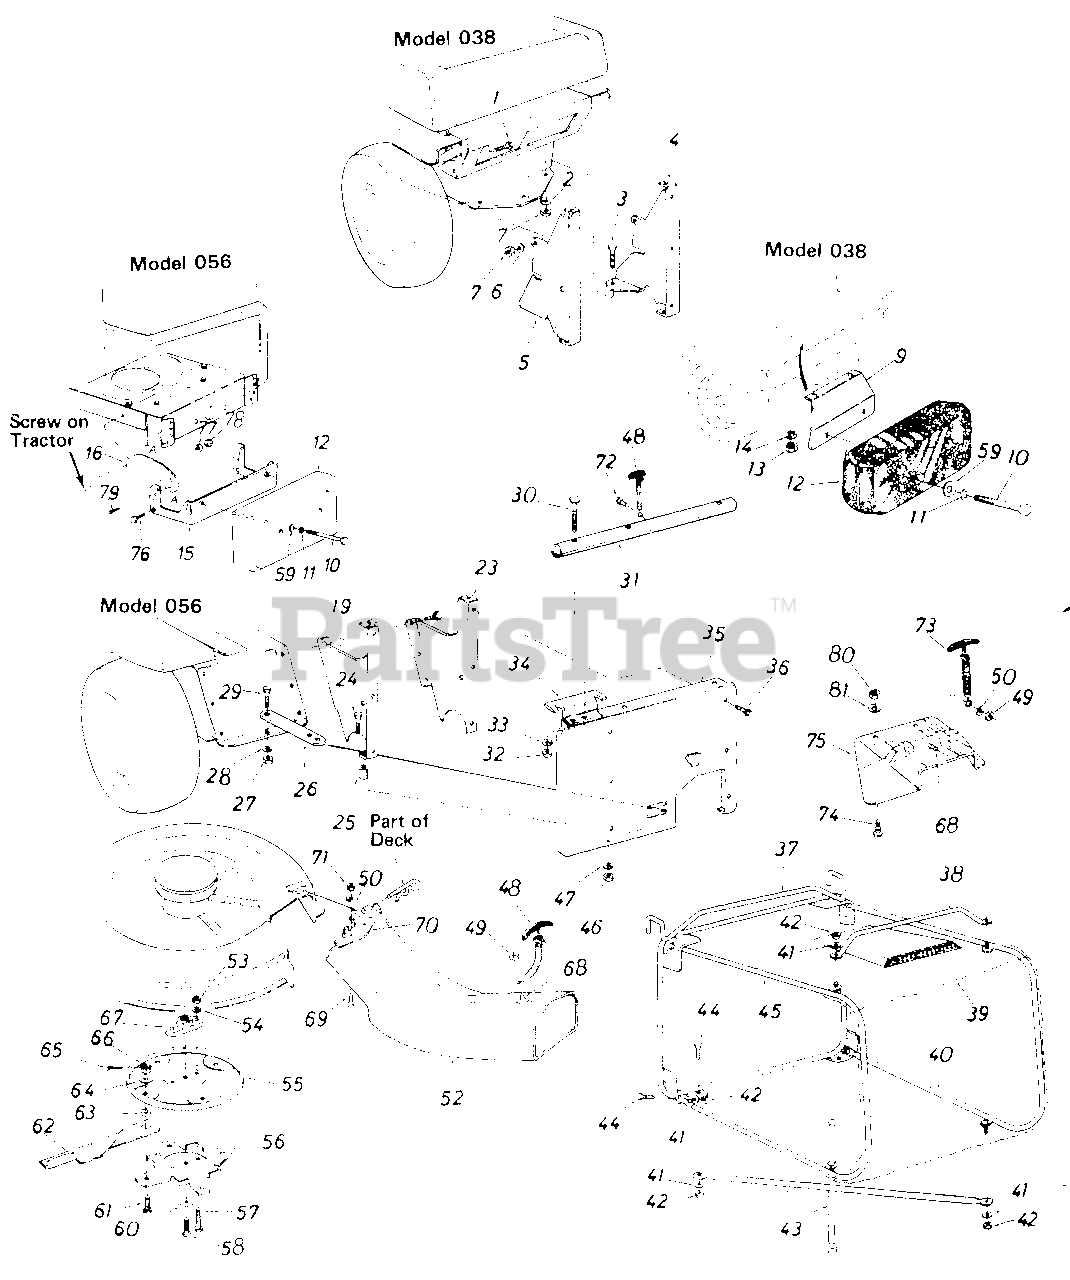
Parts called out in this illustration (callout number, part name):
1	Hex Bolt 5/16-18 x 1.0" Lg.
2	L.Wash. 5/16" I.D.
3	Hex Bolt 5/16-18 x 1.0" Lg.
4	Catcher Support Brkt R.H.
5	Catcher Support Brkt-L.H.
6	L.Wash. 5/16" I.D.
7	Hex Nut 5/16-18 Thd.
9	Counterweight Support Brkt. Ass'y .
10	Hex Bolt 3/8-16 x 4.5" Lg.
11	Beileville Wash. .40" I.D. x .88" 0. D.
12	Counterweight 38 Ibs.
13	Hex Nut 5/16-18 Thd.*
14	L.Wash. 5/16" I.D.
15	Counterweight Support Brkt. Ass'y.
16	Tie Strap
19	Catcher Support Brkt.-L.H.
23	Catcher Support Brkt.-R.H.
24	Hex Bolt 5/16-18 x 1.50" Lg."
25	Spacer .380" I.D. x .47" O.D. x 1.0" Lg.
28	L.Wash. 1/2" I.D.
29	Hex Bolt 1/2-20 x 1.0" Lg.
30	Curved Carriage i301t /16-18 x 1.75" Lg.
33	L.Wash. 5/16" I.D.
34	Grass Catcher Support Plate
35	Rear Discharge Panel
36	Hex Wash. Ild. Self Tap. Scr. 1/4- 20 x . 50" Lg.
37	Grass Catcher Frame Ass'y.
42	Hex L.Nut 1/2-20 Thd
43	Botom Cross Brace
44	Hex Bolt 1/4-20 x .62" Lg. *
47	L Wash. 5/16" I.D.
48	Hook Latch Ass'y.
49	Hex L.Nut 1/4-20 Thd.
50	Fl.Wash. 1/4" I.D.*
52	R.D. Banana Chute Ass'y.
53	Hex Nut 5/16-24 Thd.
54	L.Wash. 5/16" I.D.'
55	Upper Blade Disc
58	Hex Bolt 3/8-24 x 1.0" Lg.
59	Fl.Wash. .39" I.D. x 1.12" O.D.
60	Bell.Wash. 39" I.D. x 1.38"
61	Shld. Bolt. .50" Dia. x .360 Spec.
62	30" Blade Tip
63	Spacer .505" 1. D . x . 75" O.D. x 1.25" Lg.
64	Fl.Wash. .50" I.D. x 1.25" O.D.
65	Coter Pin 3/32" Dia. x 1.0" Lg.*
66	Hex Sloted Nut 1/2-20 Thd.
67	Blade Adapter
68	Hex Bolt 1/4-20 x .50" Lg.*
69	Truss Mach. Scr. 1/4-20 x .50" Lg. *
72	Hex AB Tap Scr. 1/4 x .62" Lg.
73	Hook Latch Ass'y. 7" Lg.
74	Truss Mach. Scr. 1/4-20 x 50" Lg.*
75	R D Chute Extension
76	Hex Bolt 7/16-20 x 1.0" Lg.*
77	L.Wash. 7/16" I.D.*
78	Hex Nut 7/16-20 Thd.*
79	Self-Tap. Scr. 5/16-18 x 1.0" Lg.
80	Hex L.Nut 1/4-20Thd.
81	Fl .Wash. .281 " I .D. x .50" O.D. .063
